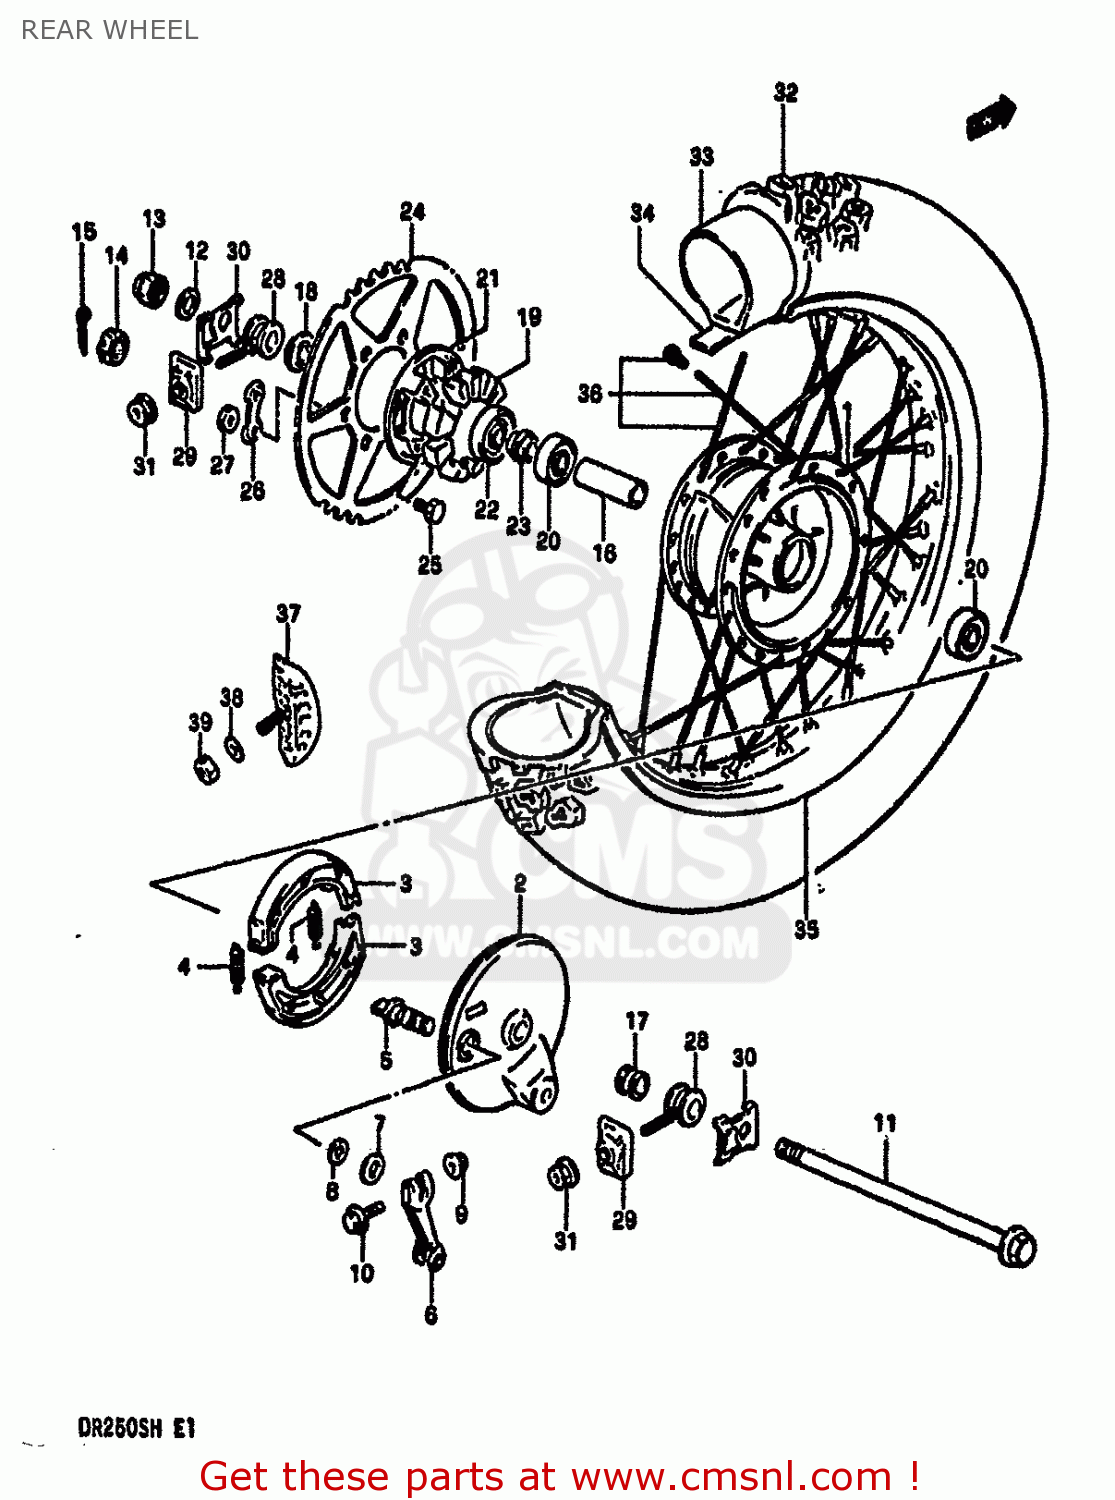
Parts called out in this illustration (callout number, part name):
1	DRUM,REAR HUB
2	PANEL,REAR HUB
3	SHOE,BRAKE
4	SPRING(L:34)
5	CAM,FRONT BRAKE
6	LEVER,REAR BRAKE CAM
7	WASHER (14.5X22X1.6)
8	O-RING (D:2.4 ID:13.8)
9	NUT
10	BOLT 6X35
11	AXLE,REAR
12	WASHER
13	NUT
14	NUT
15	PIN,COTTER
16	SPACER,REAR HUB BEARING
17	SPACER,REAR AXLE,RIGHT
18	SPACER,REAR AXLE,LEFT
19	ABSORBER,RR SHOCK
20	BEARING
21	DRUM,REAR SPROCKET MOUNT
22	BEARING
23	SPACER,REAR HUB BEARING
24	SPROCKET,RR(NT:42)
25	BOLT
26	WASHER
27	NUT
28	ADJUSTER,CHAIN
29	PLATE,CHAIN ADJUSTER
30	WASHER,CHAIN ADJUSTER GUIDE
31	NUT
32	TIRE
33	TUBE ASSEMBLY,WHEEL,INNER
34	PROTECTOR,WHEEL,INNER
35	RIM,REAR WHEEL (2.15X17)(
36	SPOKE ASSY,RR WHEEL
37	STOPPER,BEAD
38	WASHER
39	NUT
